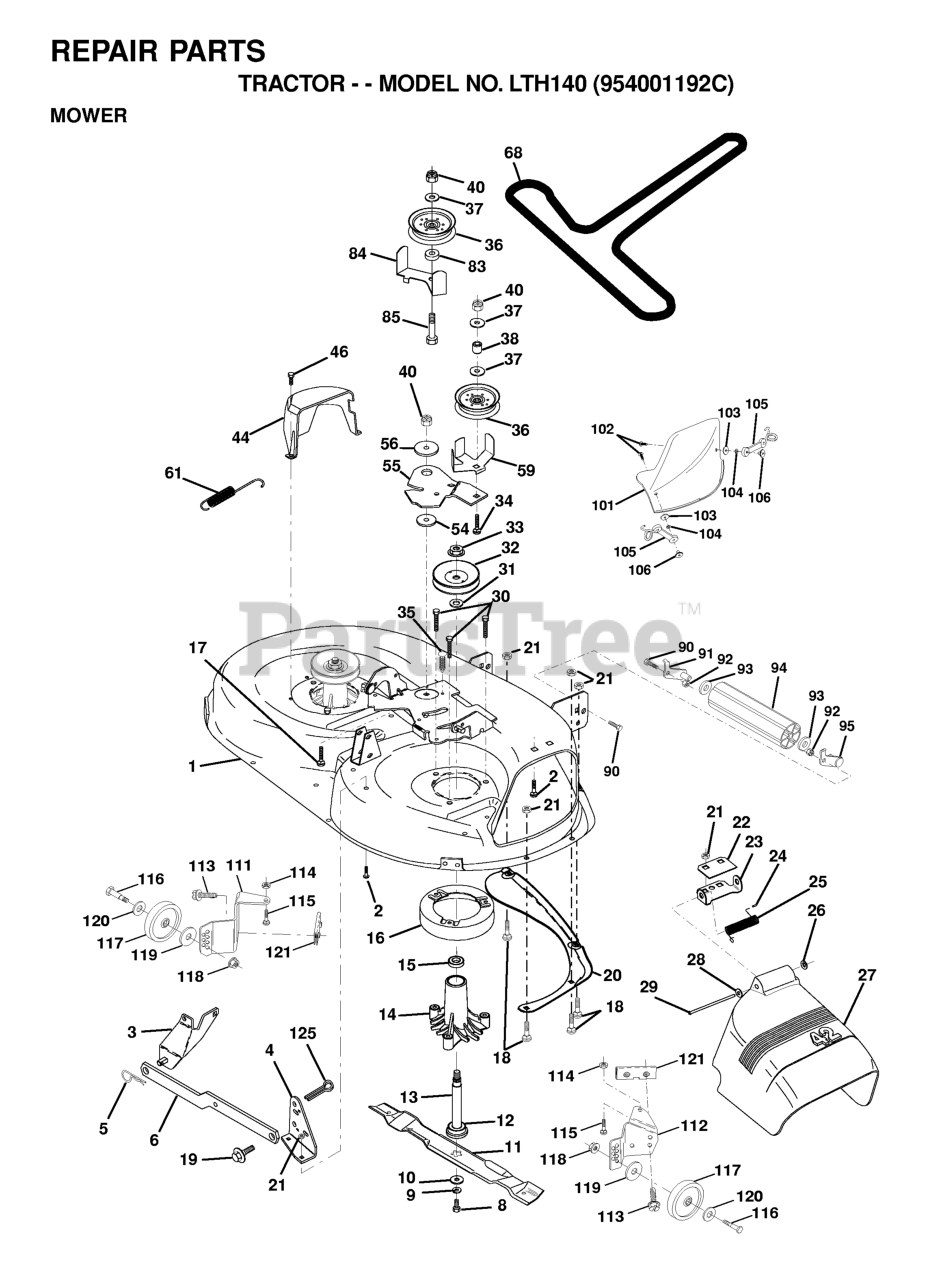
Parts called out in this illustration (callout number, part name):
1	DECK 42"
2	RP BOLT 5/16-18 X3/4 ZN/YEL GR
3	BRKT ASM SWAY BAR
4	BRKT DECK SW BAR
5	RETAINER-SPRNG RB
6	REAR SUSP ARM
8	BLADE BOLT
9	LOCKWASHER
10	WASHER.BLADE
11	BLADE.42".MULCH
12	BEARING.BALL.#6204.(MANDREL)
13	SHAFT ASM VENT
14	HOUSING.MANDREL.VENTED (MACHD)
16	STRIPPER
17	BOLT CARRIAGE
18	BOLT
19	BOLT SHD 5/16-18
20	BAFFLE
21	LOCKNUT
22	STIFFENER BRACKET
23	DEFLECTOR BRACKET
24	CAP-SLEEVE LT
25	SPRING TORSION
26	NUT PUSH M
27	SHIELD.DEFLECTOR.MOWER.42".BLK
28	Washer 11/32 x 5/8 x 16 Ga SD
29	ROD.HINGE
30	SCREW
31	WASHER
32	MANDREL PULLEY
33	NUT
35	FASTENER.XMAS.TREE
36	FLAT IDLER PULLEY
37	WASHER
38	IDLER SPRING SPACER
44	GUARD MANDREL LH BLACK
46	SCREW.1/4-20X5/8
54	HARDENED WASHER
55	IDLER ARM
56	SPACER RETAINER
59	GUARD, BELT
61	SPRING EXTENSION
68	V-BELT TRIPATH
84	KEEPER BELT
85	BOLT
90	BOLT
91	BRACKET LH (A)
92	NUT
93	Washer 1 17/32 X 7/8 X 16 Ga
94	NOSE ROLLER
95	BRACKET RH (B)
101	COVER MULCH 42"
102	SCREW
103	LOCKWASHER #10
105	LATCH ASSEMBLY
106	WELDNUT
111	BRACKET
112	BRACKET
113	SCREW.THDROL.5/16-18X3/4.TTY
114	NUT
115	BOLT.CARR.5/16-18X1/2
116	BOLT M
117	WHEEL.GAUGE.BLK.4.93
118	LOCKNUT
119	WASHER.5/16.FLAT.STE.STD.
120	Washer 17/32 x 15/16 x 12 Gauge
121	BRACKET.EXTRUDED.GAGE.WHEEL
125	Pin Cotter 1/4 x 1 Plated
